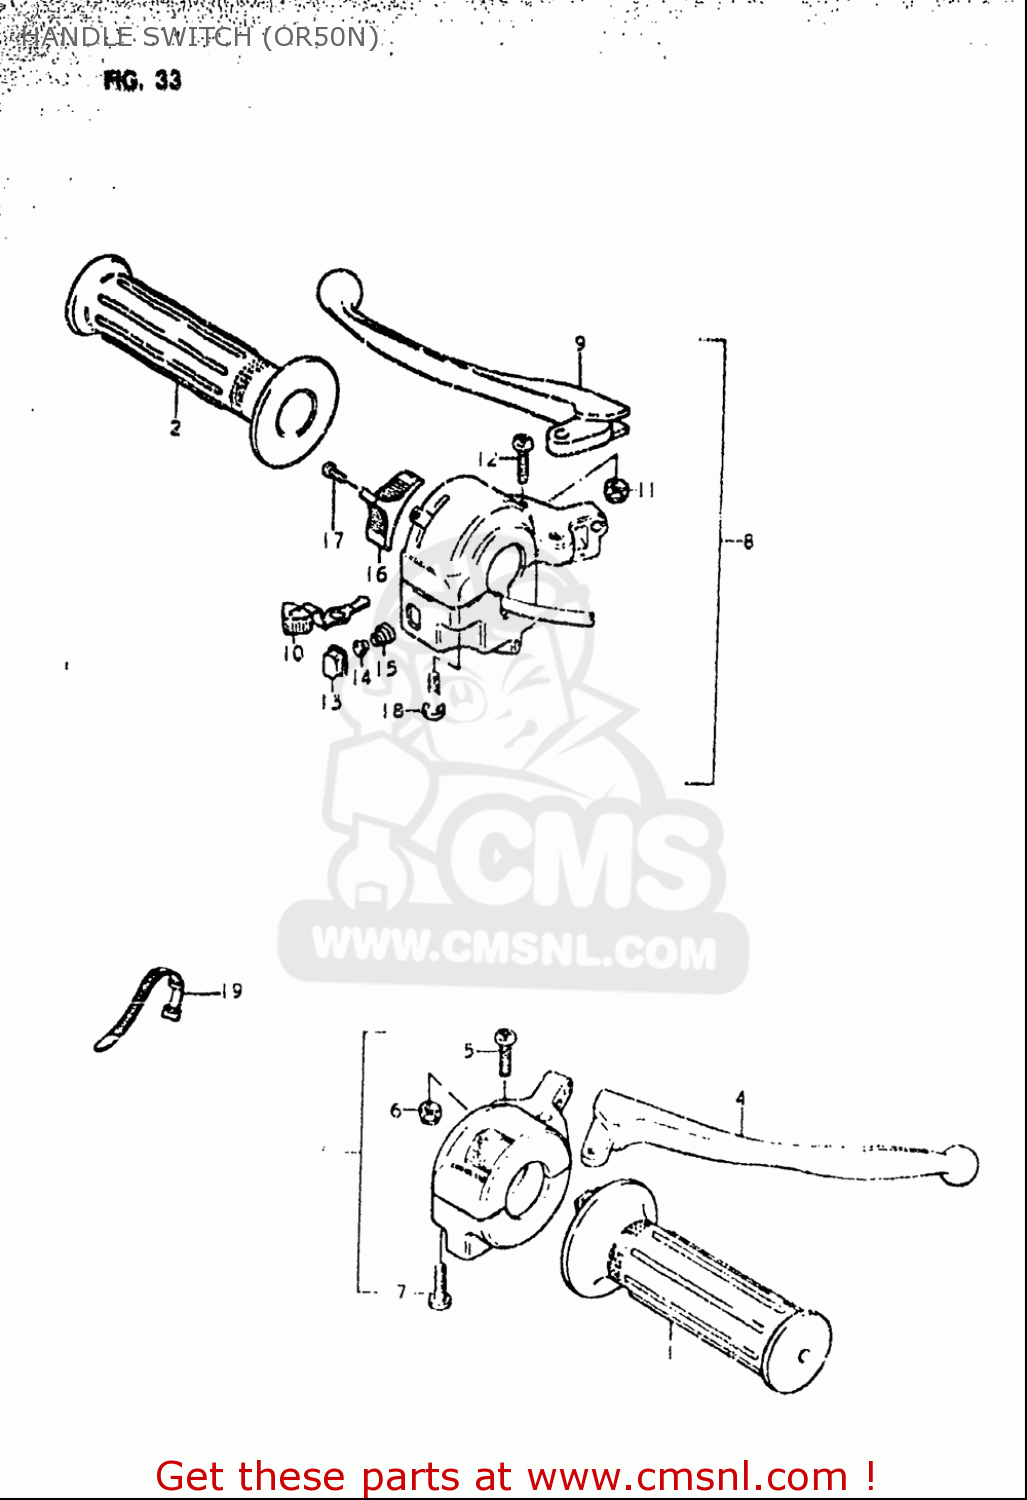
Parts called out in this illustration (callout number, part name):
1	GRIP,THROTTLE
2	GRIP,L
4	LEVER
5	BOLT,LEVER PIVOT
6	NUT
7	SCREW
8	LEVER ASSY,CLUTCH
9	LEVER
10	KNOB,TURN SIGNAL SWITCH
11	NUT
12	BOLT,LEVER PIVOT
13	BUTTON,HORN
14	CONTACT
15	SPRING
16	KNOB
17	SCREW
18	SCREW
19	CLAMP(L:120)
